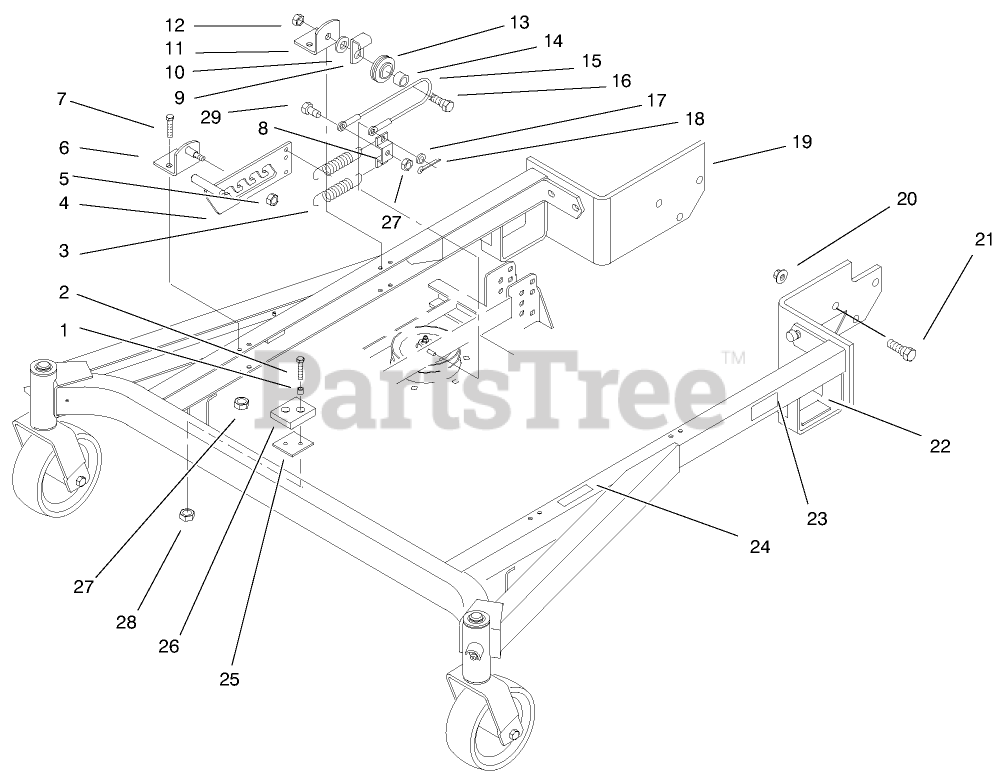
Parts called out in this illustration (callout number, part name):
1	SPACER
3	EXTENSION SPRING
4	Control-Tension
5	NUT-HF
6	Bracket-Control
7	SCREW-HH
8	SPRING BRACKET
9	CABLE RETAINER
10	THRUST WASHER
11	Bracket-Pulley
12	NUT-LOCK, NI
13	Pulley Assembly (Incl. Ref.#14)
14	BUSHING
15	CABLE
16	BOLT-SHOULDER
17	WASHER-FLAT
18	PIN-COTTER
19	Carrier Frame Assembly (Incl. Ref. #23, 24)
20	NUT-HF
21	SCREW-HHF
22	REAR RUBBER PAD
23	DECAL-HOC, LH
24	DECAL-WARNING
25	CUSHING SHIM
26	CUSHION-RUBBER
27	NUT-LOCK, NI
28	NUT-LOCK, NI
29	SCREW-HH
